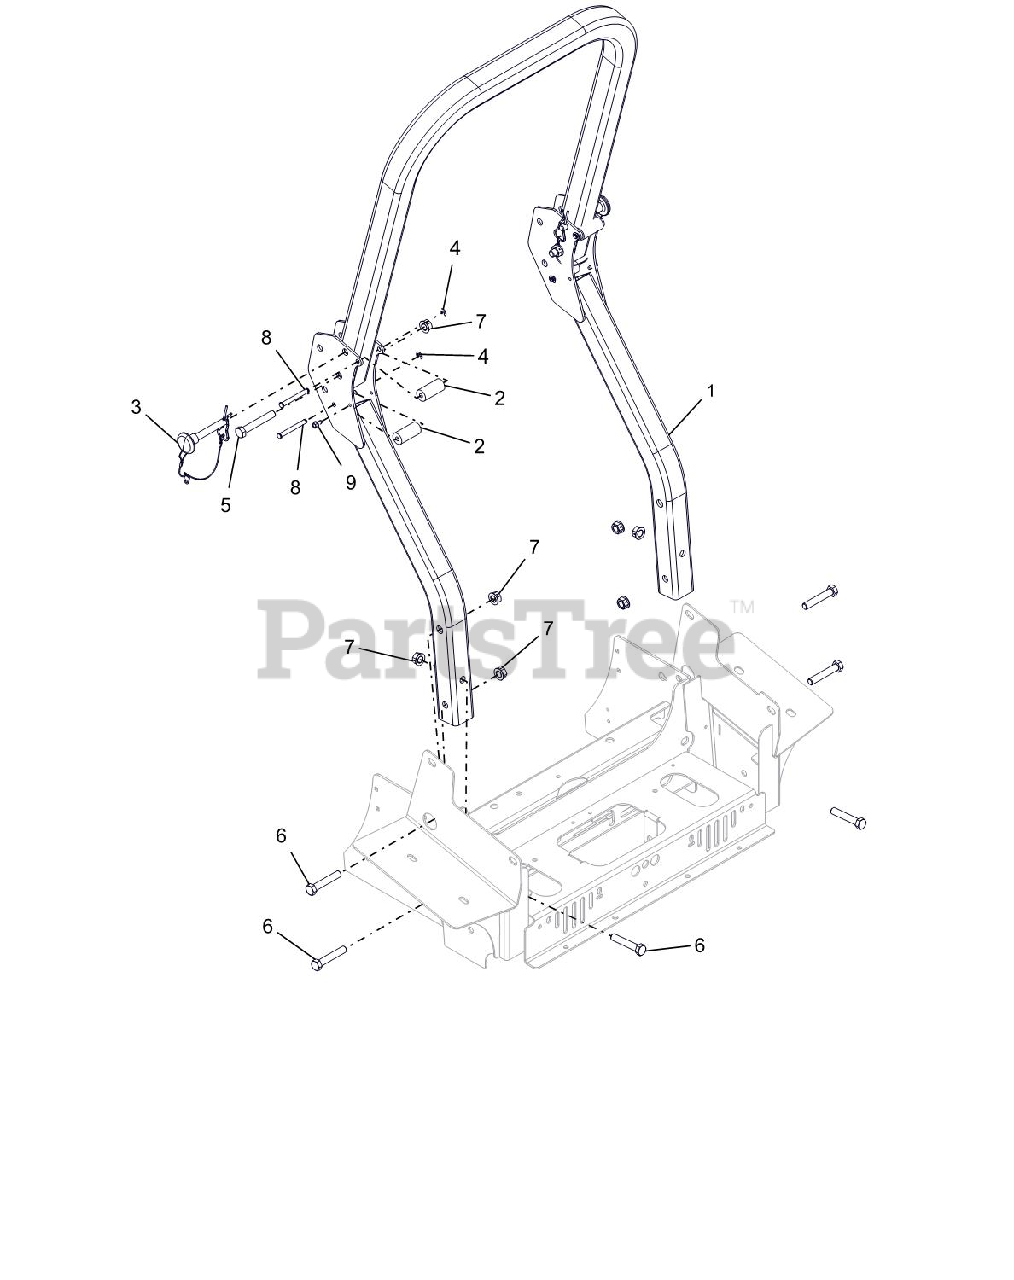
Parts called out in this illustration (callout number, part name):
1	ROPS, PT200/400 REPLACEMENT
2	BUMPER, ROPS ANTI-VIBRATION
3	PIN, ROPS W/LANYARD
4	RING, RETAINING-E .312 X .025
5	@BLT-HEX .50-13X3.25 GR5 YWZC
6	@BLT-HEX .50-13X2.75 GR5 YWZC
7	NUT-LK-CTR-FLG .50-13 YWZC
8	PIN, 5/16 X 2-9/16 WITH GROOVE
9	SCR-TAP .25-20X.50 HWH TR YWZ
